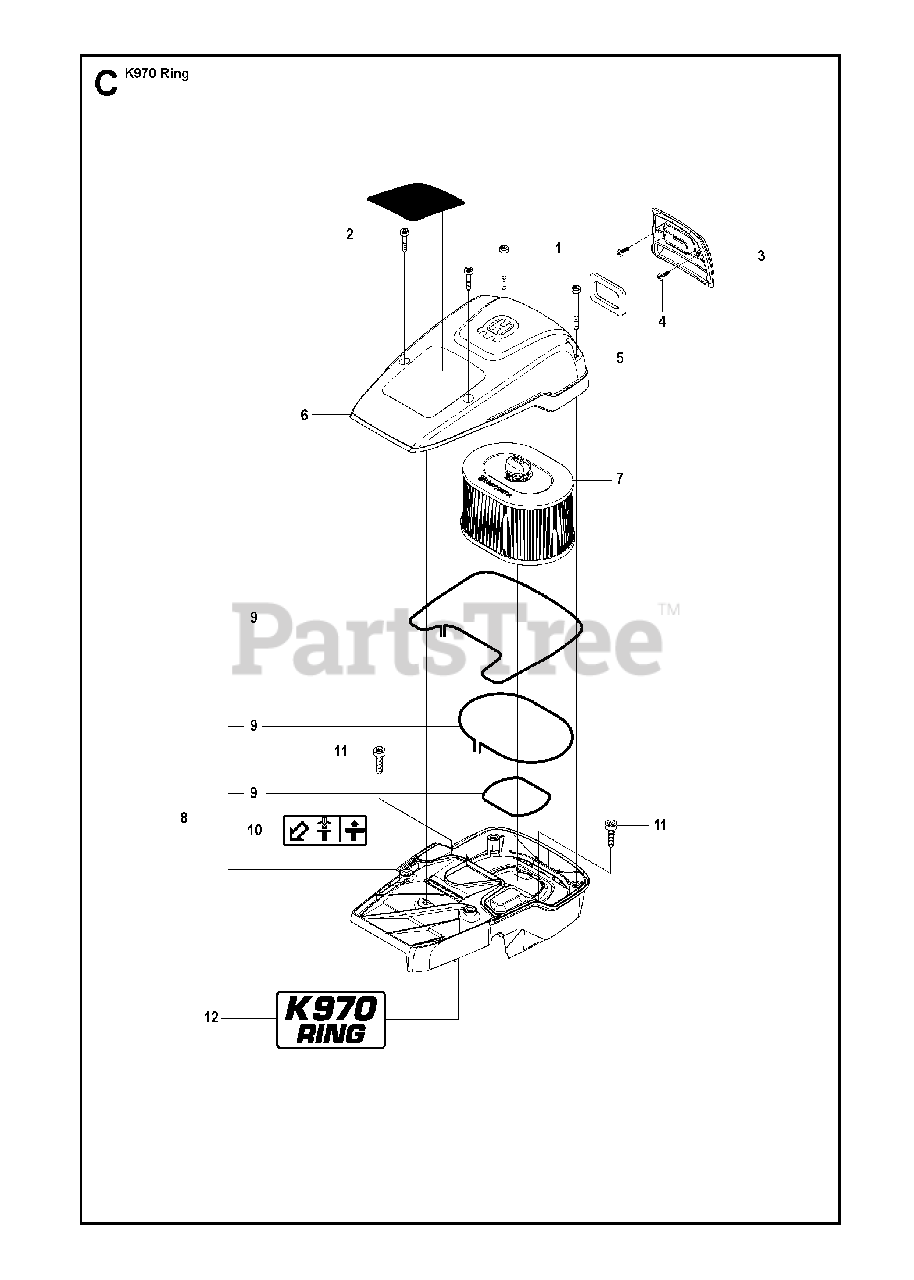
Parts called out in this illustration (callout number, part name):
1	SCREW ITXSCM
2	SCREW ITXSCM
4	SCREW CRPANT
7	AIR FILTER
8	CYLINDER COVERIncl. 9 - 10
9	SEALINGL=1,2 M. Cut to fit
11	SCREW ITXSCM
